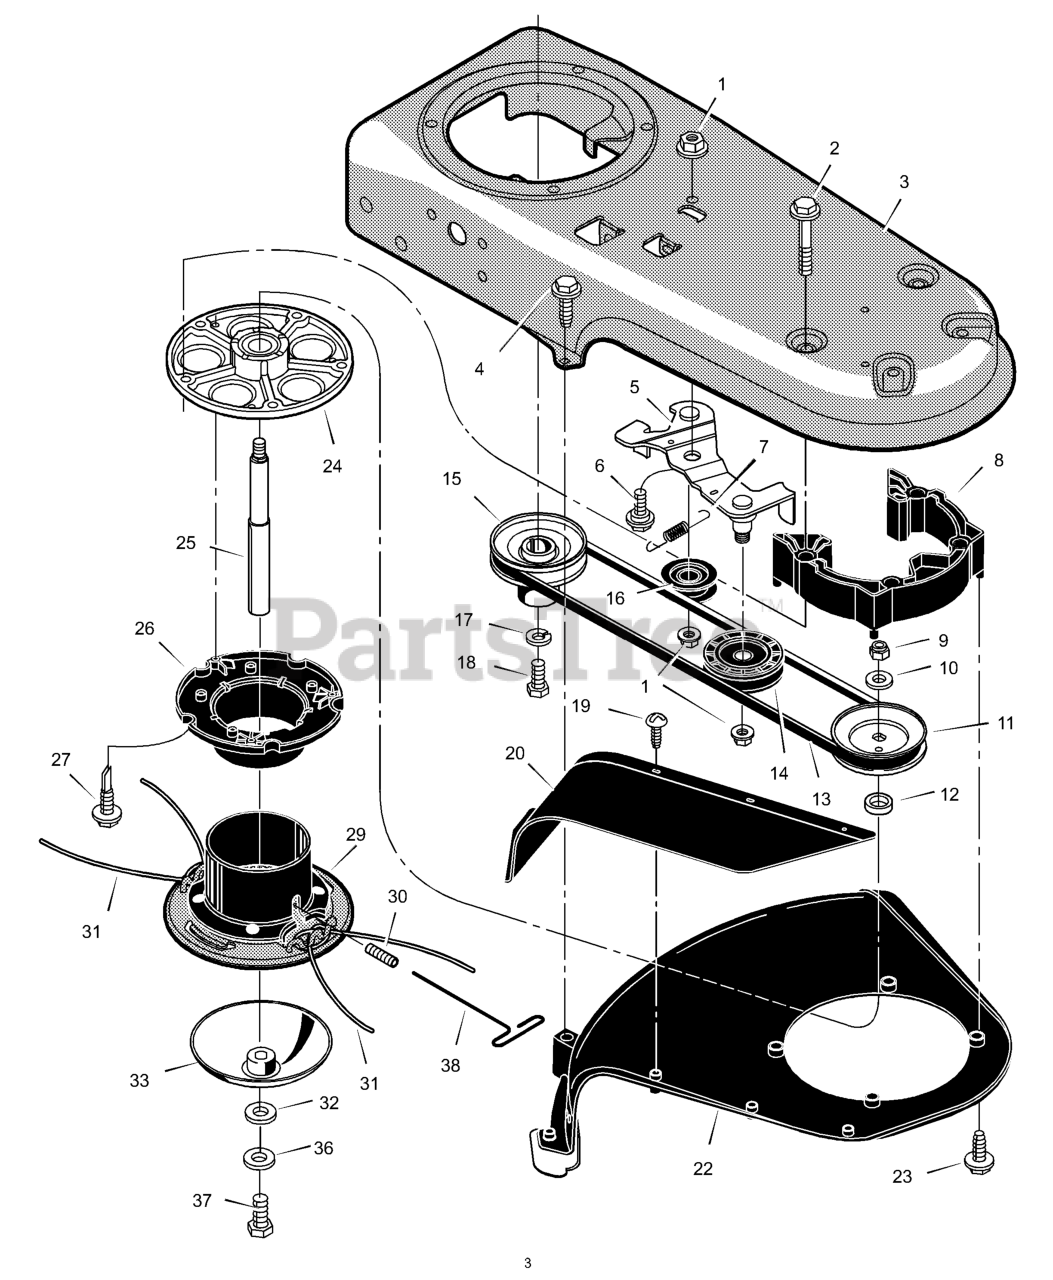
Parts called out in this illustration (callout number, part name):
1	Nut
2	Screw
5	Bracket, Idler Assembly
7	Spring, Extension
8	Spacer Assembly, Jackshaft
10	Washer, Flat
11	Pulley, Cutting Head
12	Spacer, Upper Pulley
13	Belt, Trimmer
14	PULLEY, IDLER, V, 1.88
15	Pulley, Engine
16	Pulley, Idler
17	Lockwasher
20	Flap, Debris
22	Shield, Trimmer
24	Housing, Jackshaft
25	Shaft, Cutting Head
26	Wrap, Weed
29	Assembly, Cutter Head & Wrap
30	Screw, Set
31	Line, Trimmer 0.155 X 21.25
32	Flatwasher
33	Guide, Metal Height
36	Lockwasher
38	Wrench, T-Handle
